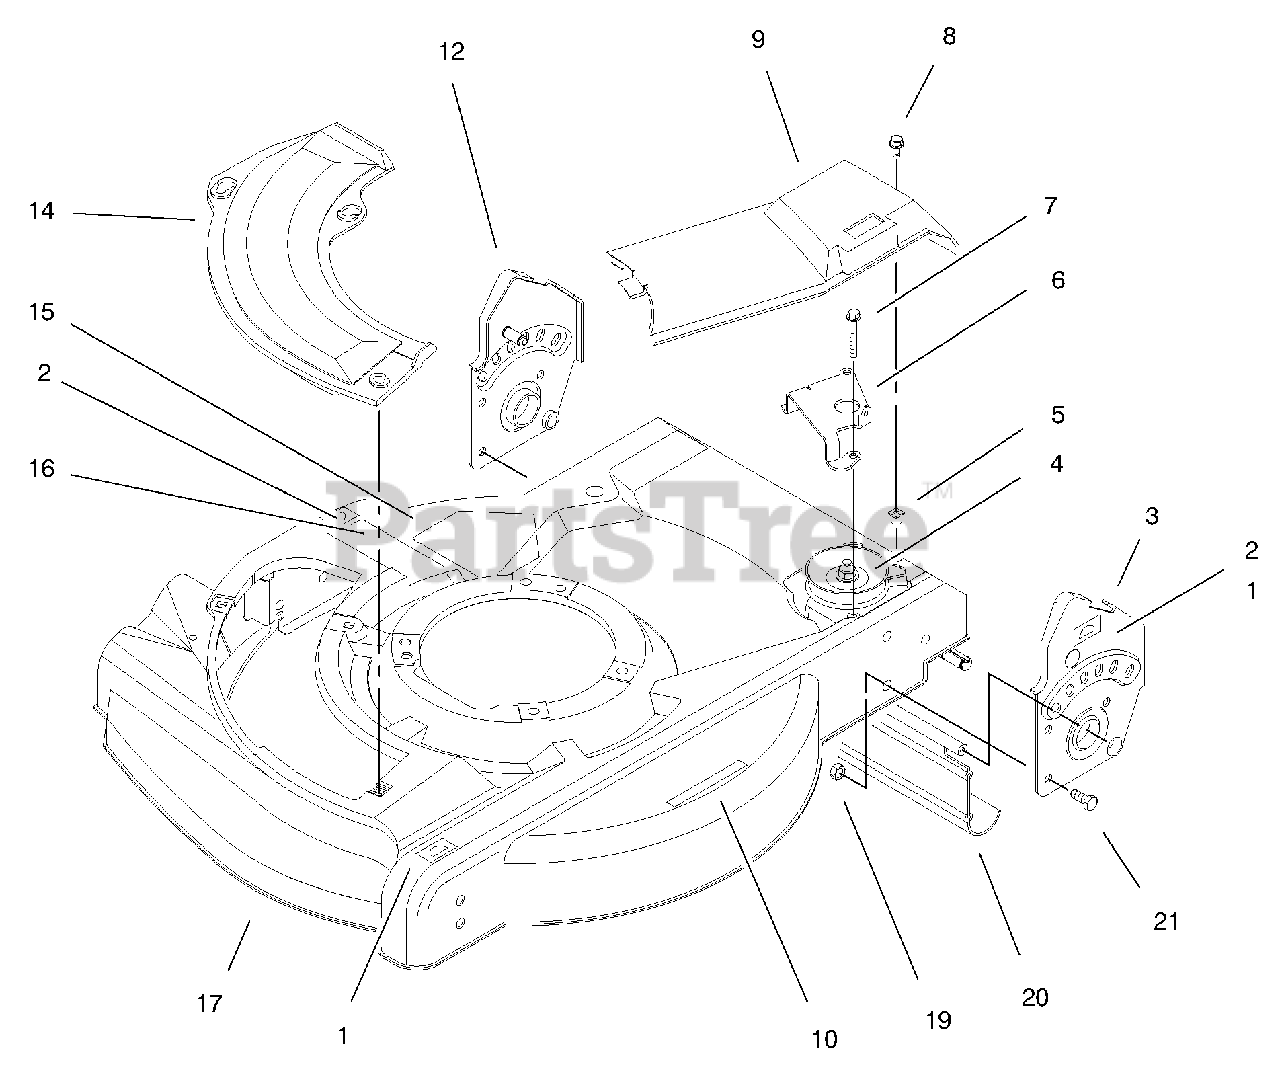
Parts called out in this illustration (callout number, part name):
1	Decal-H.O.C.
2	Decal-H.O.C.
3	Bracket-Handle L.H.
4	Gear Case Assembly
5	Grommet
6	Guide-Transmission
7	Screw-Hex Hd.
8	Screw-Phillips Hd.
9	Cover-Drive
10	Decal-Warning
12	Bracket-Handle R.H.
14	Plate-Cover
15	Decal-Danger
16	Decal-Discharge
17	Housing Assembly
19	Nut-Lock
20	Shield-Trailing
21	Screw-Hex Hd. Cap
